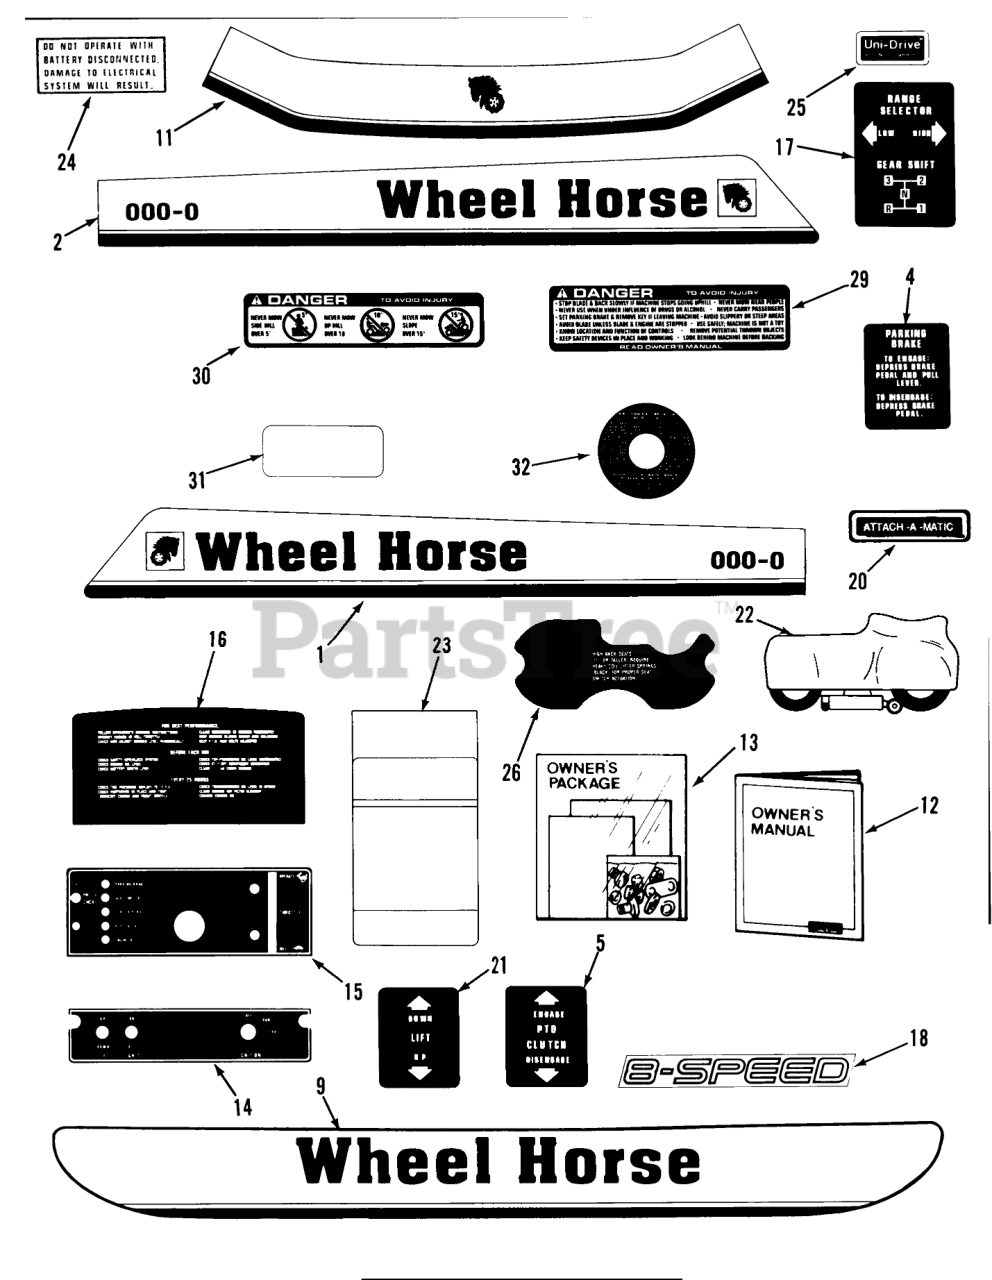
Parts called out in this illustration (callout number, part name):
1	DECAL-HOOD 310-8 R H
1	Decal-Hood RH 312
1	DECAL-HOOD 414-8 R H
1	DECAL-HOOD 416-8 R H
2	Decal-Hood LH 310
2	DECAL-HOOD 312-8 L H
2	DECAL-HOOD 414-8 L H
2	DECAL-HOOD 416-8 L H
4	DECAL-PARKING, BRAKE
5	DECAL PTO CLUTCH
5	DECAL PTO
9	DECAL-FENDER
11	DECAL-FRONT HOOD
12	Owners Manual-Tractor
13	Loose Parts Package 310
13	Loose Parts Package 312
13	Loose Parts Package 414
13	Loose Parts Package 416
14	DECAL BACK PLATE
15	Decal-Lower Dash 310
15	DECAL LOWER DASH
15	Decal-Lower Dash 416
16	DECAL-REAR HOOD
17	DECAL-SHIFT PATTERN
18	DECAL 8SPD
20	Decal-Attac-O-Matic
21	DECAL-LIFT
21	DECAL LIFT
22	Vinyl Tractor Cover
23	MAINTENANCE-DECAL
24	DECAL ELECT SYSTEM
25	Decal-Unidrive
26	DECAL-SEAT LIFTER
29	Decal-Danger
30	Decal-Danger
31	DECAL-OVERLAY
32	Decal-Air Cleaner
